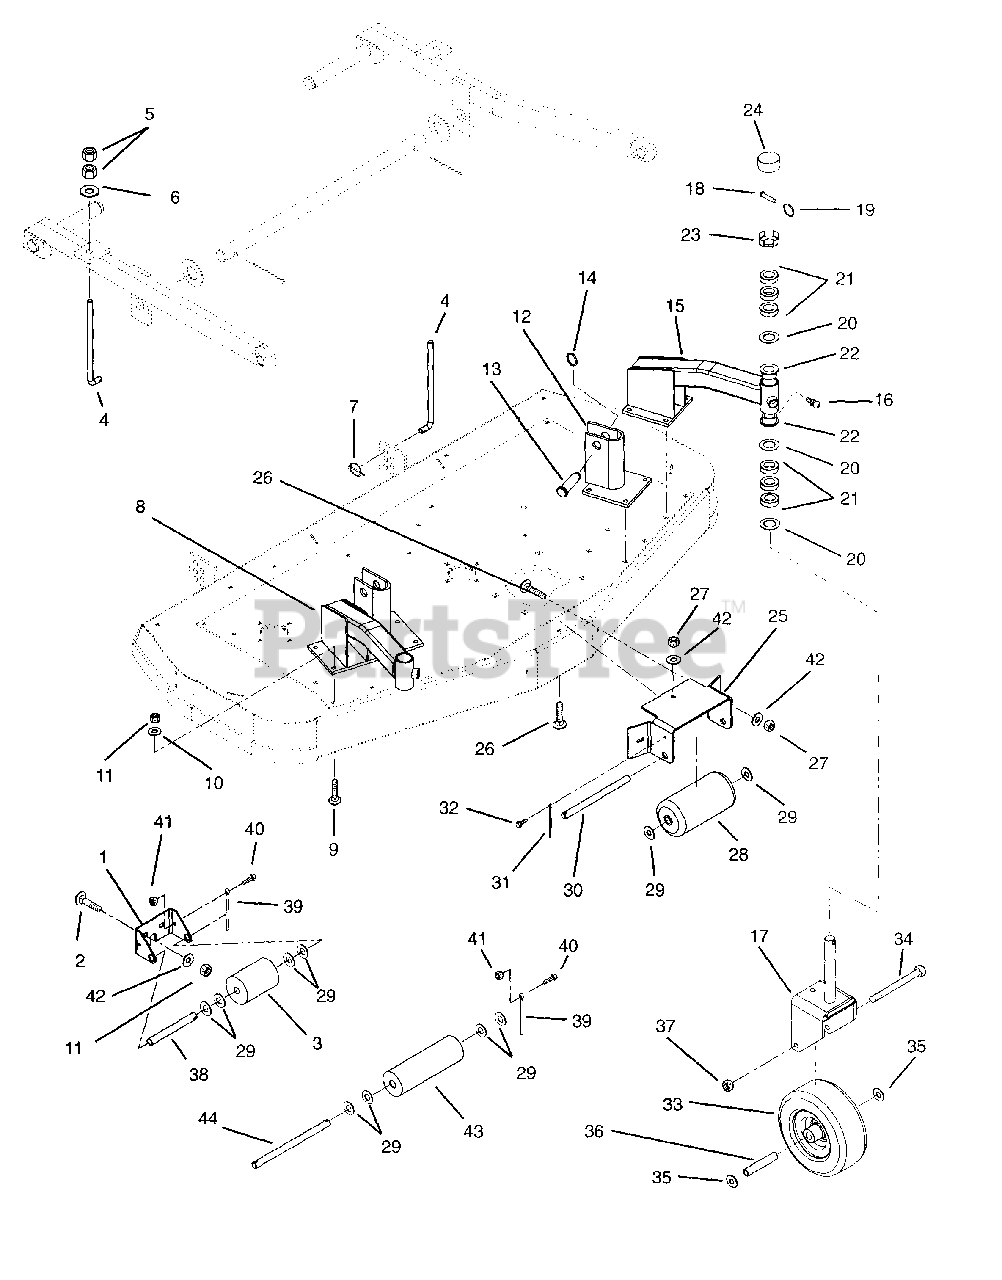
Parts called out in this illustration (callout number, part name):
1	Bracket-Roller
2	Bolt-Round Head Square Neck .38-16 x .75 Grade 2
3	Roller-Gauge
4	Rod, Rear Height Adjuster
5	Nut-Hex .50-13
6	Washer-Flat-Steel .531 x 1.06 x .095
7	Pin-Klik 1.000 x .188 x 1.25
8	Right Hand Lift Arm
9	Bolt-Round Head Square Neck .38-16 x 1.25 Grade 2
10	Washer-Flat-Steel .406 x .812 x .065
11	Nut-Locking-Center .38-16
12	Lift Arm Mount Weldment, Left Hand
12	Weldment, Lift Arm Mount Left Hand 50"
13	Pin-Clevis .875 x 3.00
14	Ring-Retaining-External 1.062 x 1.25
15	Support Arm Weldment
16	Fitting-Lube .25-28 x .256
17	Weldment, Caster Fork
18	Pin-Clevis .309 x 1.625 Grade 5
19	Ring-Retaining-External 1.062 x 1.25
20	Washer-Hardened-Thrust 1.00 1.55 x .03
21	Bushing-Sleeve 1.04 x 1.75 x .500
22	Bushing-Flange 1.020 x 1.385 x .75 x 1.75 Nylon
23	Spindle Cup
25	Anti-Scalp Roller Bracket
26	Bolt-Round Head Square Neck .31-18 x .75
27	Nut-Locking-Center .31-18
29	Washer-Flat-Steel .656 x 1.31 x .095
31	Pin-Cotter .25 x 2.25
32	Screw-Tapping .25-20 x .50 Hex Washer Head
33	Wheel
34	Bolt-Hex .50-13 x 5.50
35	Washer-Hardened-Thrust .760 x 1.25 x .094
36	Bearing .750 x .532 x 3.94
37	Nut-Locking-Center .50-13
38	Rod
39	Pin-Cotter .25 x 2.00
40	Bolt-Hex .25-20 x .75 Grade 5
41	Nut-Locking-Center .25-20
42	Washer-Flat-Steel .38 x .875 x .083
43	Roller, Gauge
44	Shaft, Center Roller
